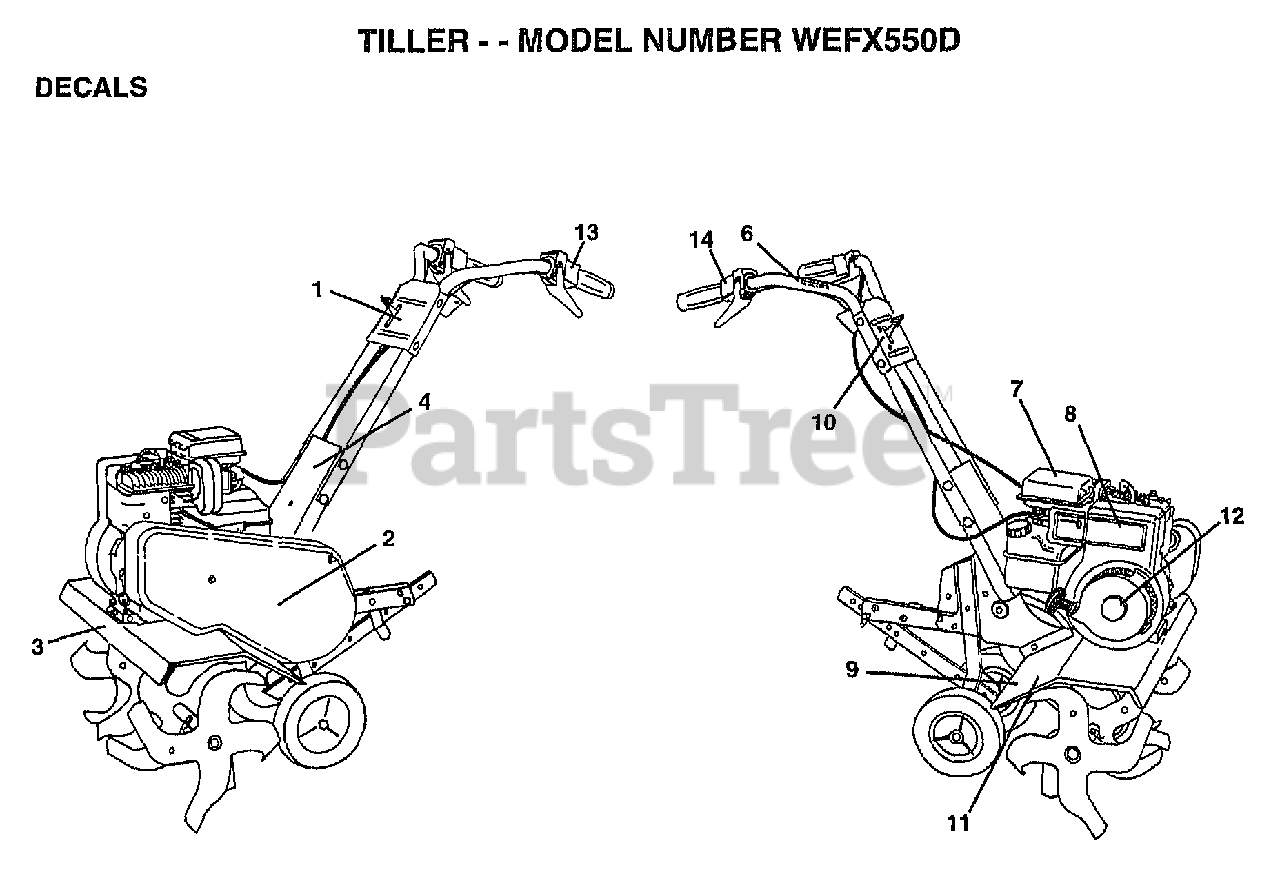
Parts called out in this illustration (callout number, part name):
1	DECAL.LOGO.CONTROL
3	DECAL.DESCRIPTION
4	DECAL.HP.REVERSE
6	DECAL-PLACEMENT
7	DECAL TI
9	DECAL-WARNING
10	"DECAL CONTROL,PNL"
11	DECAL.EURO.ST.CE.
13	DECAL.CONTROL FOR
14	DECAL.CONTROL.REV
